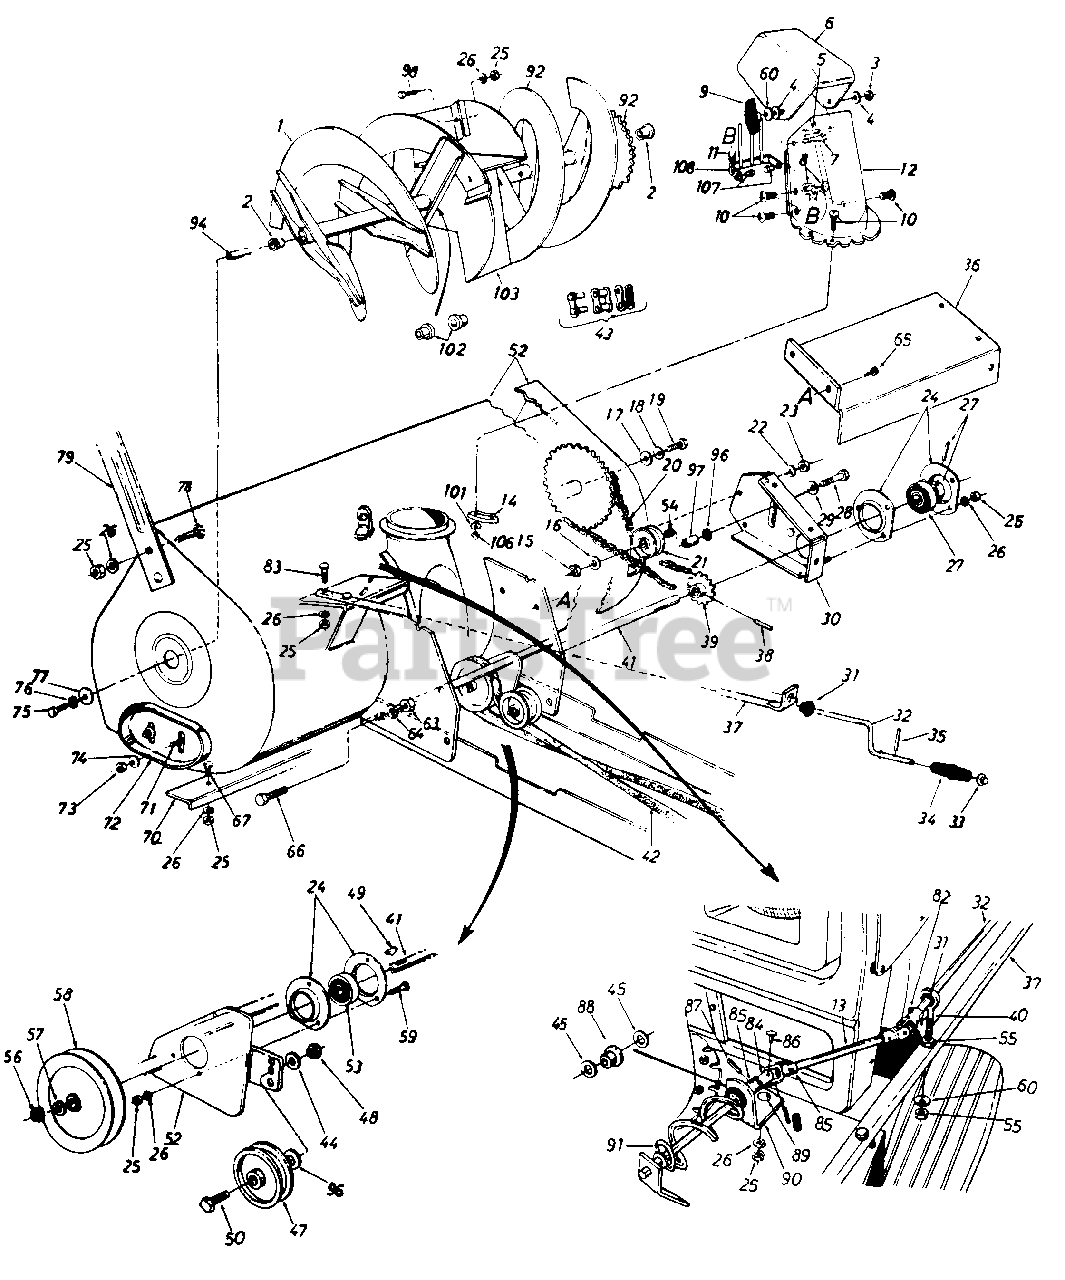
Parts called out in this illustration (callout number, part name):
3	Hex Cent. L.-Nut 5/16-18 Thd.
4	Fl.-Wash. .344" I.D.
5	Truss Mach. Scr. 5/16-18 x .75" 4.
6	Upper Chute
7	Carriage Bolt 5/16-18 x 1.0" Lg.*
8	Hex L-Nut 1/4-20 Thd.
9	Hand Knob
10	Truss Mach. Scr. 1/4-20 x .75" Lg.
11	Ext. Spring
12	Lower Chute
13	Chute Crank Extension Rod
14	Chute Flange Keeper
15	L.-Nut 3/8-16 Thd.
16	Fl.-Wash.
17	Fl.-Wash.
18	Belleville Wash.
19	Hex Bolt 1/2-13 x 1.00" 4.
20	#420 Chain 1/2" Pitch x 77 Links
21	Plastic Idler 2.00" O.D.
22	L.-Wash. 1/4" I.D.
23	Hex Nut 1/4-20 Thd.
24	Bearing Housing
25	Hex Nut 5/16-18 Thd.
26	L.-Wash. 5/16" I.D.
27	Self-Aligning Bearing
28	Hex Bolt 3/8-16 x 1.75" 4.
29	Belleville Wash. 3/8" I.D.
32	Chute Crank .375 Dia. x 34.5" 4
33	Push Nut 3/8" Rod
34	Knob (Black)
35	Roll Pin
39	14 Teeth Sprocket Ass'y.
40	Eyabolt 5/16-18 x 3.0" Lg.
41	Dri Shaft
42	"V"-Balt
43	Master Link for #420 Chain
44	L.-Wash. 3/8" I.D.
45	Fl.-Wash..385 I.D. x .62" O.D.
47	Fl.-Idler with Flanges
48	Hex Jam L.-Nut 3/8-16 Thd.
49	#61 Hi-Pro Key 3/16 x 5/8 Dia.
50	Hex Bolt 3/8-16 x 1.75" 4.
52	Spiral Housing Ass'y.
53	Self-Aligning Bearing
54	Sleeve Bearing .50" I.D.
55	Hex Nut 5/16-18 Thd.
56	Hex Nut 3/4-10 Thd.
57	L.-Wash. 3/4" I.D.
58	"V"-Pulley .750" I.D. x 6.00" O.D.
59	Hex Sems Bolt 5/16-18 x .75" 4.
60	Bell.-Wash. .345" I.D. x .88" O.D.
63	Hex Nut 1/2-13 Thd.
64	L.Wash. 1/2" I.D.
65	Hex Wash. Hd. Tap Scr. 1/4-20 x .50" 4.
66	Hex Bolt 1/2-13 x 2.75" Lg.*
67	Carriage Bolt 5/16-18 x .75"
72	Skid Shoe
73	Hex Jam Nut 3/8-16 Thd.
74	Belleville Wash. 3/8" I.D.
75	Hex Bolt 1/2-13 x 1.00" 4.
76	Belleville Wash. 1/2" I.D.
77	Fl.-Wash.
78	Carriage Bolt 5/16-19 x .62" Lg.*
82	Cotter Pin
83	Hex Bolt 5/16-18 x 1.50" Lg.*
84	Joint Block
85	Joint Bracket Ass'y.
86	Oval Head Rivet
87	Spring Pin Roll 1/8" Dia. x .75" Lg.*
88	Nylon Bushing
89	Carriage Bolt 5/16-18 x .75" Lg.
90	Chute Crank Bracket
91	Chute Crank Ass'y.
96	Flat Washer
97	Idler Spacer
98	Carriage Bolt 5/16-18 x .75" Lg.
101	Fl.-Wash. 1/4" I.D.
102	Plastic Bushing
107	Shld. Nut 1/4-20 Thd.
05139A-0637	BLADE-GUIDE (DRIFT - POWDER BLACK (0637)
05139A-0638	BLADE-GUIDE (DRIFT - MTD/TROY-BILT RED (0638)
05139A-0662	BLADE-GUIDE (DRIFT - OYSTER GRAY (0662)
05139A-0665	BLADE-GUIDE (DRIFT - YARDMAN GREEN (0665)
05139A-0674	BLADE-GUIDE (DRIFT - YARDMAN YELLOW (0674)
05139A-0716	BLADE-GUIDE (DRIFT - CUB YELLOW-99 (0716)
